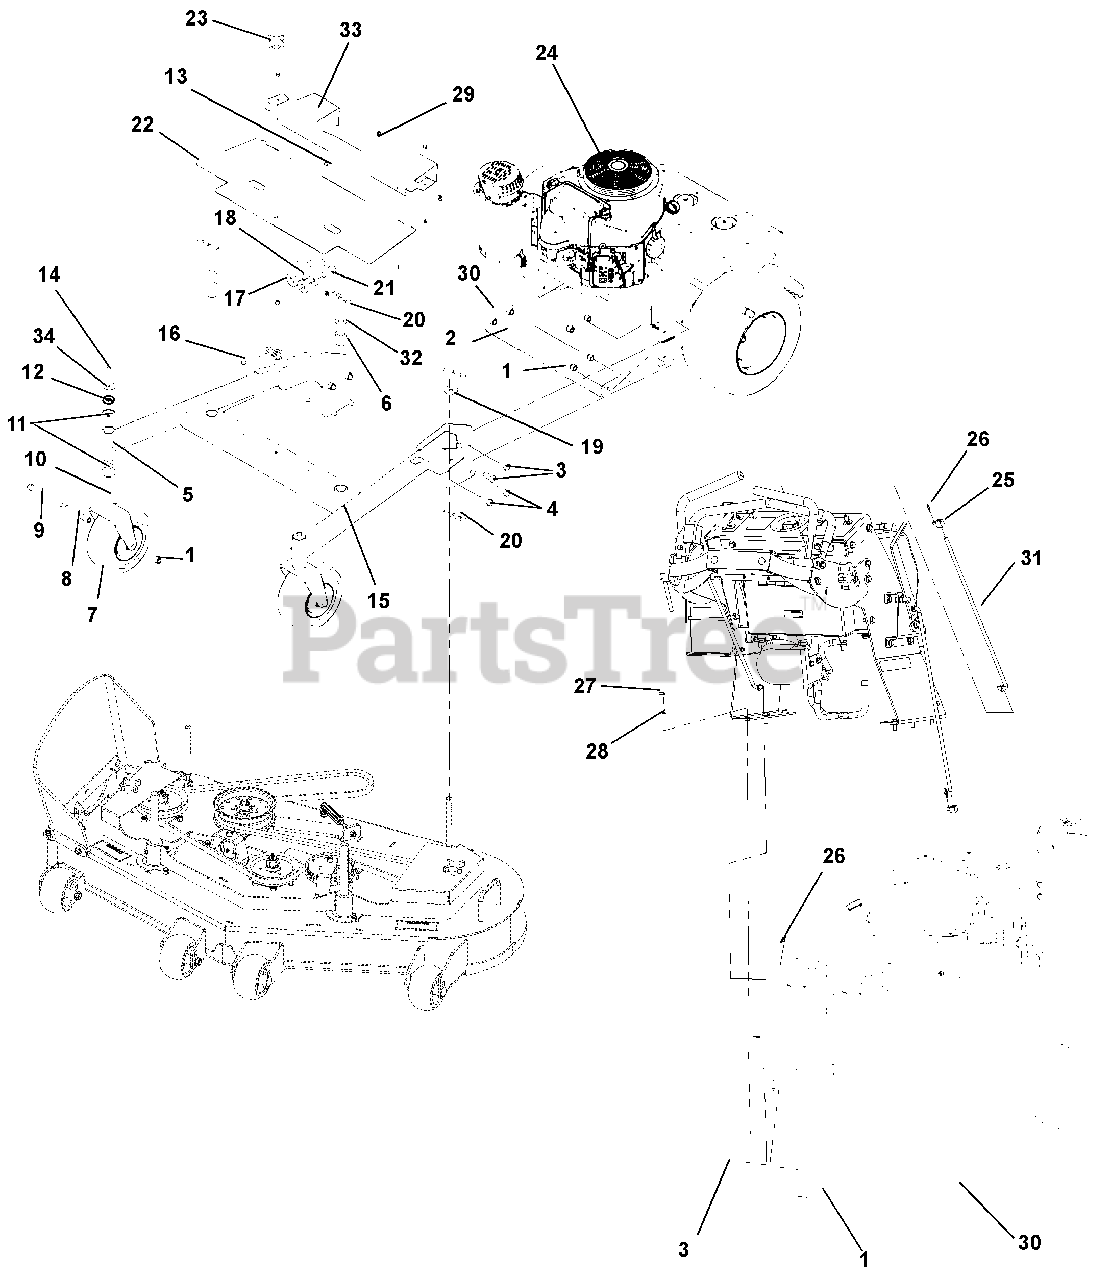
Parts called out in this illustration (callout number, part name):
1	LOCKNUT, 1/2-13 NYLOC Y
2	PLATE, ENGINE BED FRONT (988154, 155, 157, 158)
3	BOLT, 1/2-13 X 1.25 HEX 5 Y
4	BOLT, 1/2-13 X 1.50 HEX 5 Y
5	FTG, 1/4-28 STRGT GREASE ZERK
6	BSHG, FLG 1.00 X 1.25 X 1.50 X 1.50 EP REV
7	9X3.5-4 CAREFREE BLT TOGETHER
8	TUBE, CASTER AXLE
9	BOLT, .50-13 X 5.50 HEX 5 Y
10	WLDT, FRONT WHEEL FLOAT WALK
11	BRG, FLG 1.00X1.25X1.00
12	WSH-FL-ST .38 X 1.50 X .125 REV
13	BOLT, HEX .25-20 x .75 GR5
14	BOLT, .38-16 X 1.25 HEX 5 Y
15	WLDT, DECK FRAME 52 FLWLK (988155, 158)
16	BUMPER GROMMET .125 X .25 REV
17	WASHER, .905 X 1.750X.250
18	WASHER, FLAT .630 x 1.50 x .25
19	WASHER, FLAT-STEEL .688 X 1.75 X.134 REV
20	PIN, HAIR-INTERNAL .17 X .68 X 3.50 REV B
21	BOLT, 5/8-11 X 1.50 HEX 8 Y
22	SHIELD, BELT 52 MAIN (988155, 158) (SN 000101 - 020999)
23	KNOB, 3/8 X 1.25 - 4 Prong (000101 - 020000)
24	CABLE TIE, .15 X 8.50
25	SWIVEL, 3/8-24
26	RING, RUE .375 X .054 x 1.254
27	BOLT, .38-16 X 1.00 HEX 5 Y (988154, 155, 157, 158)
28	WASHER, .406 X .813 X .065 FLAT Y
29	NUT, LOCK NYLON .250-20
30	PLATE, ENGINE BED REAR (988154, 155, 157, 158, 159, 169)
31	ROD, DRIVE CONTROL FW (000101 - 020000)
32	WASHER, FL-STL REV
33	SHIELD, BELT 52" (988155, 158) (SN 000101 - 020999)
34	WSHR-LK .38X.094 REG YWZC
